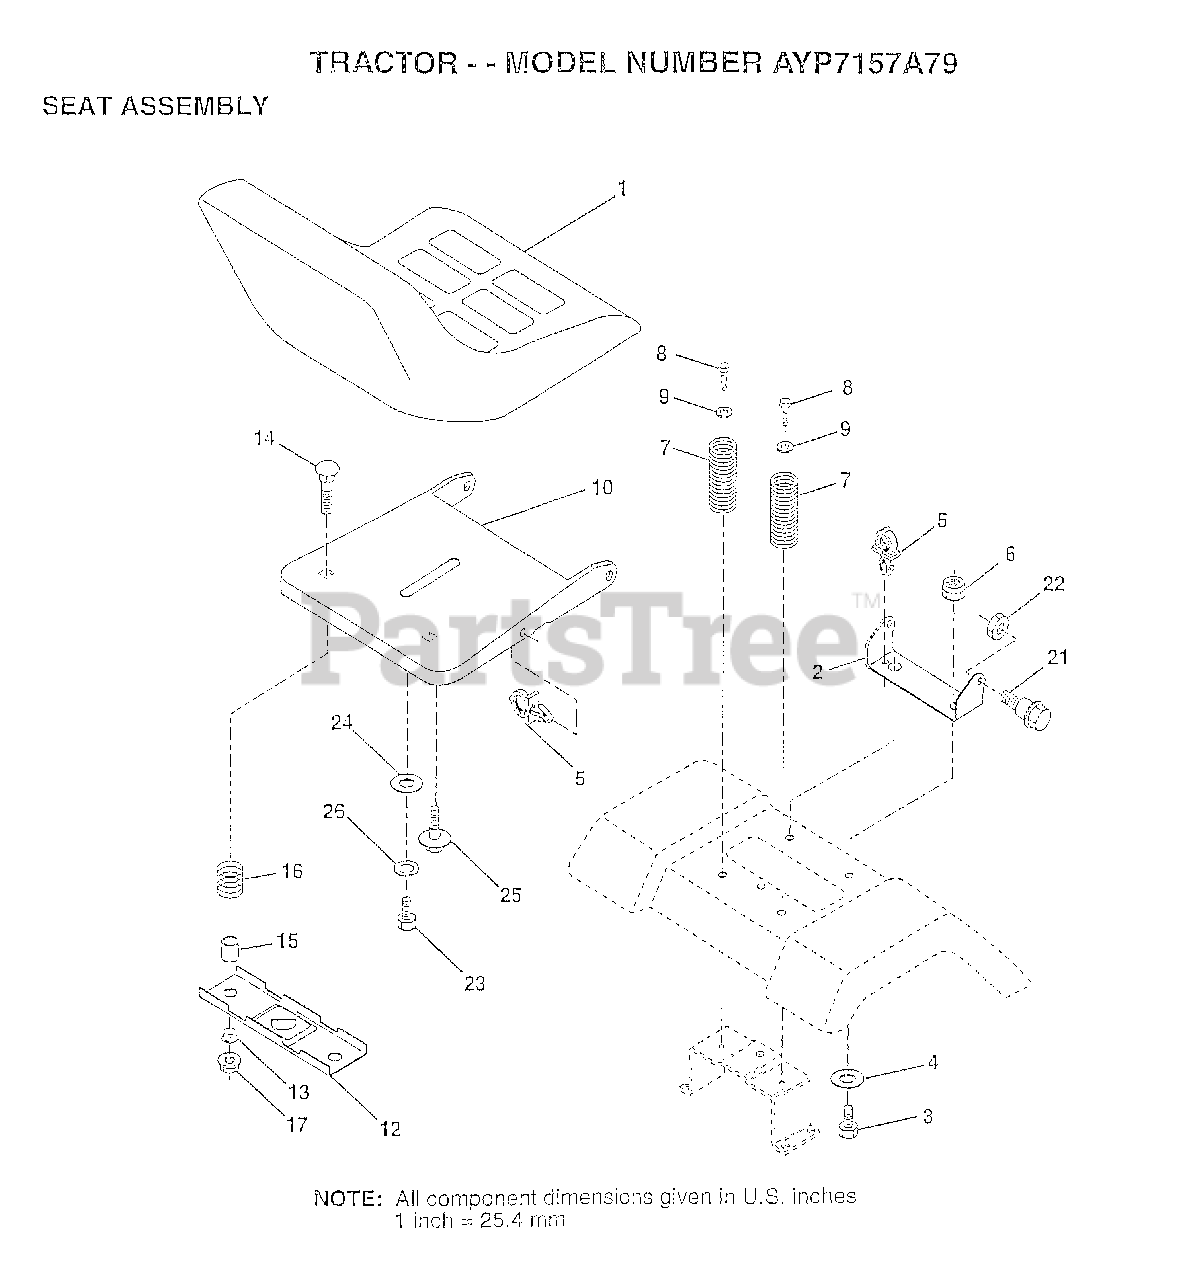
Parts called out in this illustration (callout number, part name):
1	SEAT.2400/1416.BK
2	BRACKET PVT SEAT
3	BOLT
4	WASHER PM
5	CLIP.PUSH-IN.HING
6	NUT
7	SPRING COMPRESSIO
8	SCREW GTV
9	WASHER
10	PAN-SEAT
12	BRKT SWITCH
13	BUSHING
15	SPLIT SPACER
16	SPRING
21	"BOLT,SHOULDER"
22	NUT
23	BOLT
24	WASHER
25	"BOLT,SHOULDER"
26	LOCKWASHER
